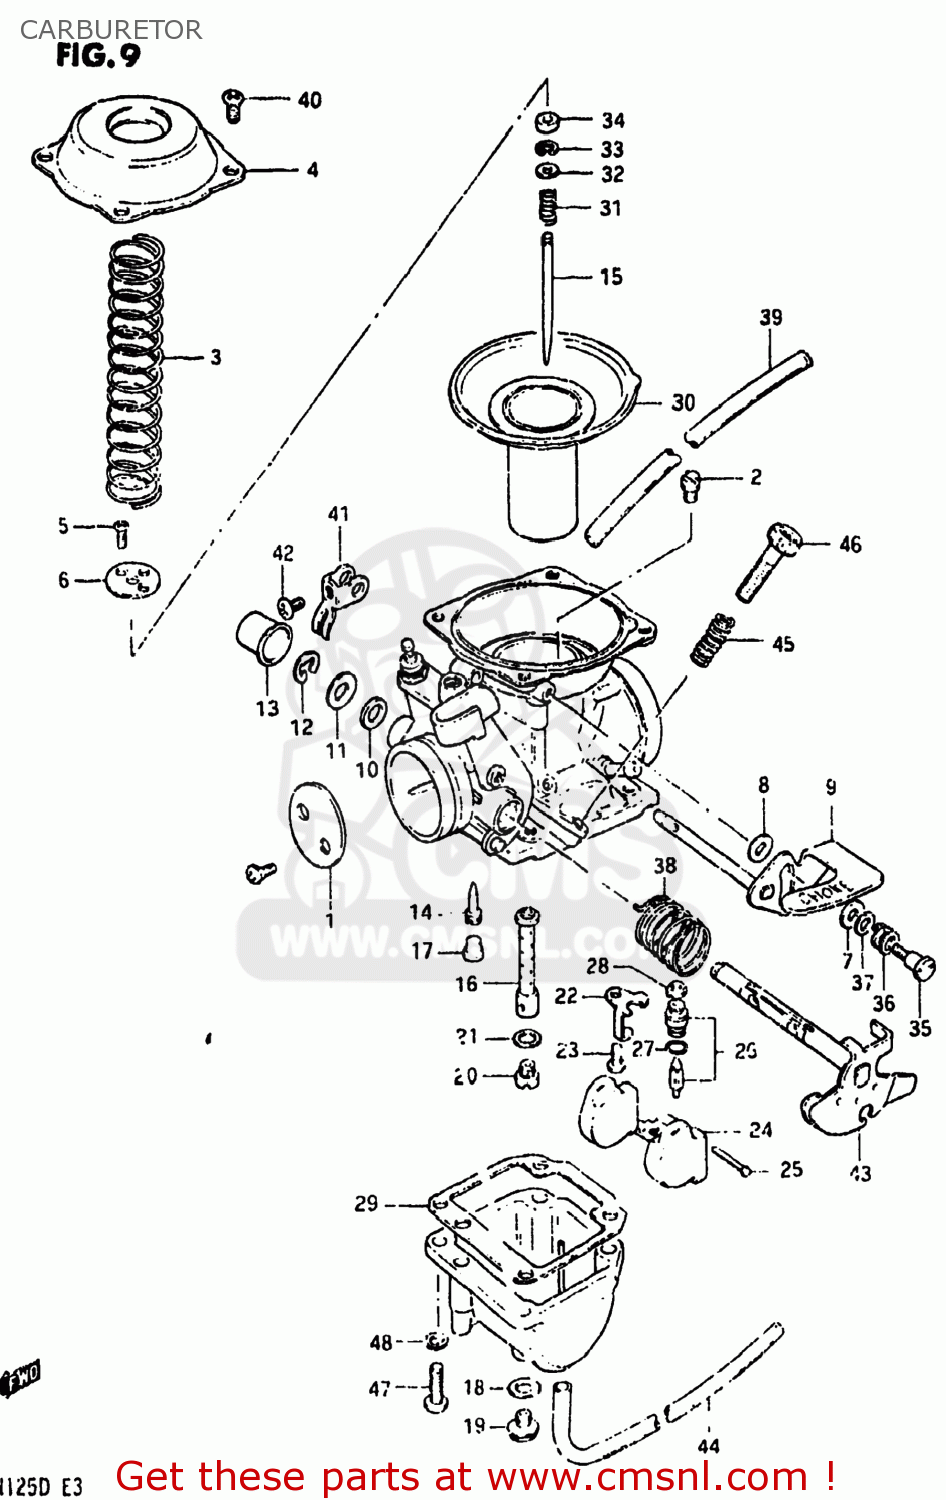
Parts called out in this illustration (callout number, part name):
1	VALVE,THROTTLE
2	JET,MAIN(180)
3	SPRING
4	COVER
5	SCREW
6	PLATE
7	PACKING (NAS)
8	WASHER,STARTER LEVER (4.1X12X0.8)
9	SHAFT ASSY,STARTER
10	SEAL
11	GASKET,THROTTLE SHAFT (NAS)
12	E RING
13	CAP
14	JET,PILOT(35)
15	NEEDLE,JET
16	JET,NEEDLE(P-2)
17	PLUG,NEEDLE JET
18	GASKET (NAS)
19	PLUG,DRAIN
20	JET,MAIN(102.5)
21	WASHER
22	PLATE,NEEDLE VALVE FITING
23	SCREW 4X6
24	FLOAT
25	PIN,FLOAT
26	VALVE ASSEMBLY,NEEDLE
27	O RING
28	FILTER
29	GASKET,FLOAT CHAMBER (NAS)
30	DIAPHRAGM ASSEMBLY
31	SPRING
32	WASHER
33	CLIP
34	RING
35	SCREW
36	SPRING
37	WASHER
38	SPRING,THROTTLE SHAFT
39	HOSE
40	SCREW
41	LEVER
42	SCREW
43	SHAFT,THROTTLE
44	HOSE
45	SPRING,THROTTLE SCREW
46	SCREW,THROTTLE STOP
47	SCREW
48	LOCK WASHER
